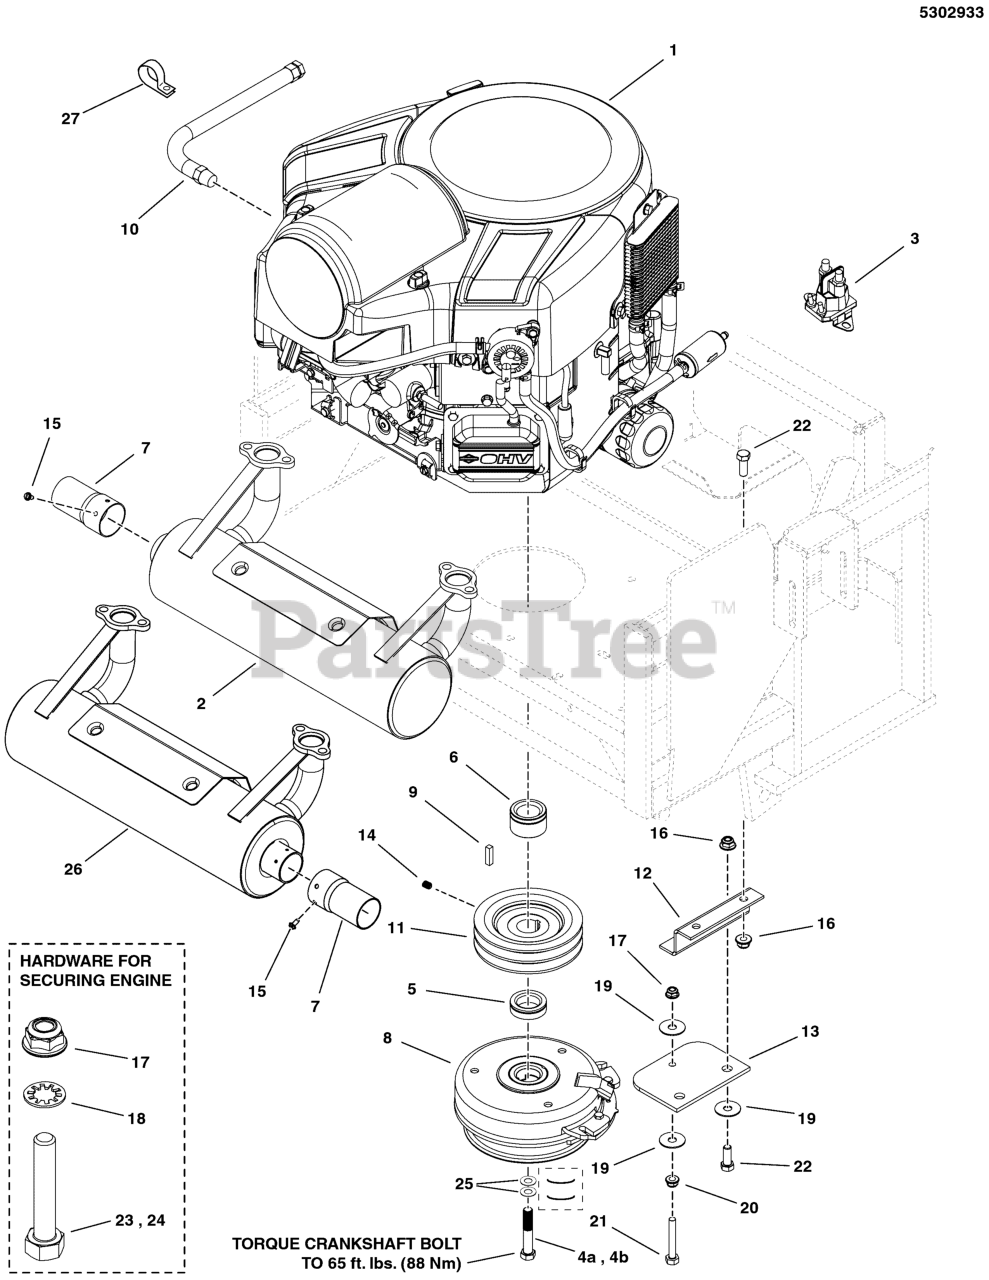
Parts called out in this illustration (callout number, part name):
1	ENGINE, B&S, COMM TURF
2	MUFFLER
3	SOLENOID-4 POLE 12 VOLT DC (TROMBETTA)
5	SPACER, 1.13 X 1.75 X .50
6	SPACER, 1.13 X 1.75 X 1.09, PM
7	EXTENSION, TAILPIPE, 3" - BLACK
8	CLUTCH,5218-221, WARNER
9	KEY, 1/4 SQ X 1
10	HOSE, OIL DRAIN
11	PULLEY, CRANKSHAFT, 1.126 ID X 4.75 OD
12	ANCHOR, CLUTCH - BLK
13	CLUTCH ANCHOR PAD
14	SET SCREW, 5/16-18 X 3/8, KNURL
15	SCREW,SELF-TAP,#8-32 X 3/8,WASH HEX, CZ
16	NUT, 3/8-16 HEX NYLOCK FLANGE
17	NUT, 5/16-18 HEX NYLOCK FLANGE
18	WASHER, 5/16 INT. TOOTH LOCK
19	WASHER-3/8 FENDER
20	NUT, 5/16-18 HEX SERRATED FLANGE (SMALL)
21	BOLT, 5/16-18 X 2-1/4 TFL, GD5 YZ
22	BOLT, 3/8-16 X 1" GD5 CZ
23	BOLT, 5/16-18 X 2, GD5
24	BOLT, 5/16-18 X 1-3/4 GD5 YZ
25	BELLEVILLE WASHER 1.1875 X .442 X .089
26	MUFFLER, RIGHT OUTLET ASSY
27	CLAMP, VINYL INSULATED
